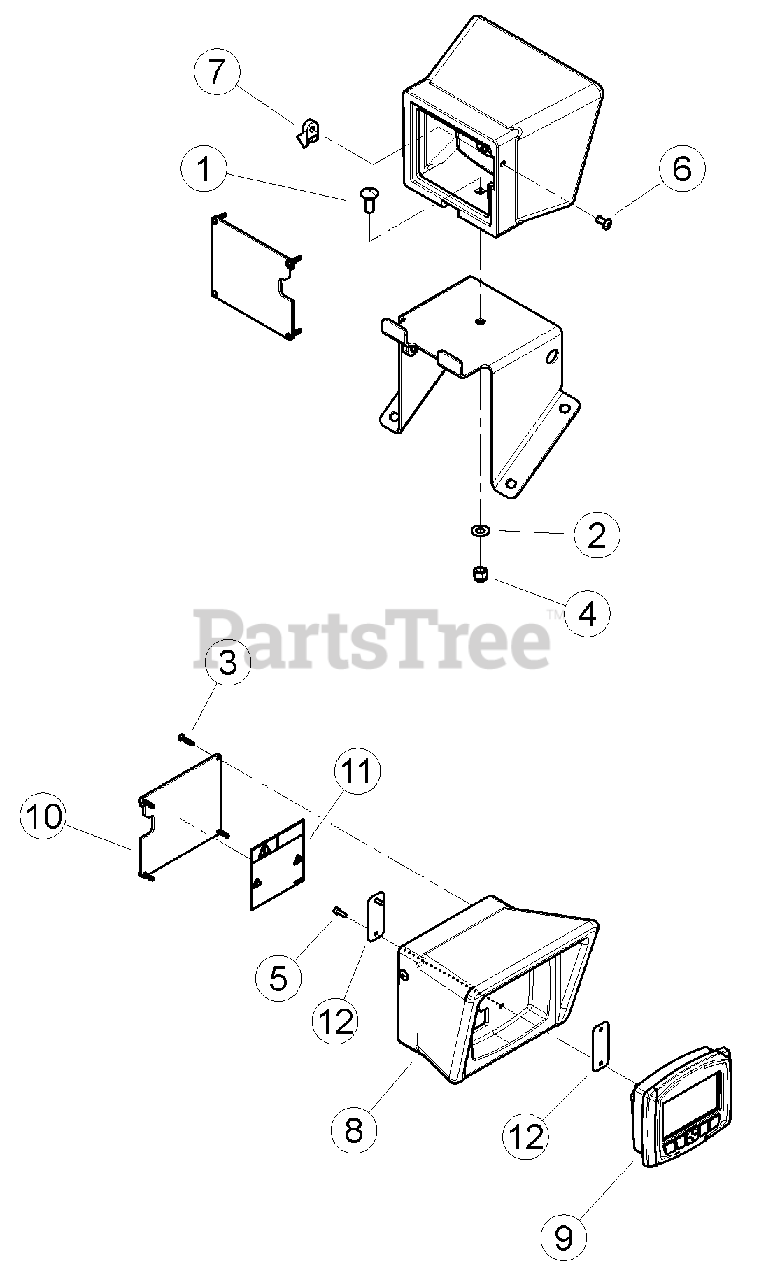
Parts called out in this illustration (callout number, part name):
1	BOLT, 3/8 X 1" GR5 CRG NC ZP
2	WASHER, 3/8" SAE FLAT ZP
3	SCREW, 10-16 3/4 LONG FOR PLASTIC
4	NUT, 3/8" NE NYLOCK ZP
5	SCREW, #8-32 X 1/2 SKT HD CAP
6	RIVET, AL BLIND 1/4 X 3/4 DOME HEAD
7	CLAMP, CABLE MOUNT
8	ENCLOSURE, CONTROLLER
9	CONTROLLER, CL-709-100 MASTER
10	ASSEMBLY, ENCLOSURE COVER WITH DECAL
11	DECAL, DDC MOUNTING INFO
12	PLATE, DDC WASHER
